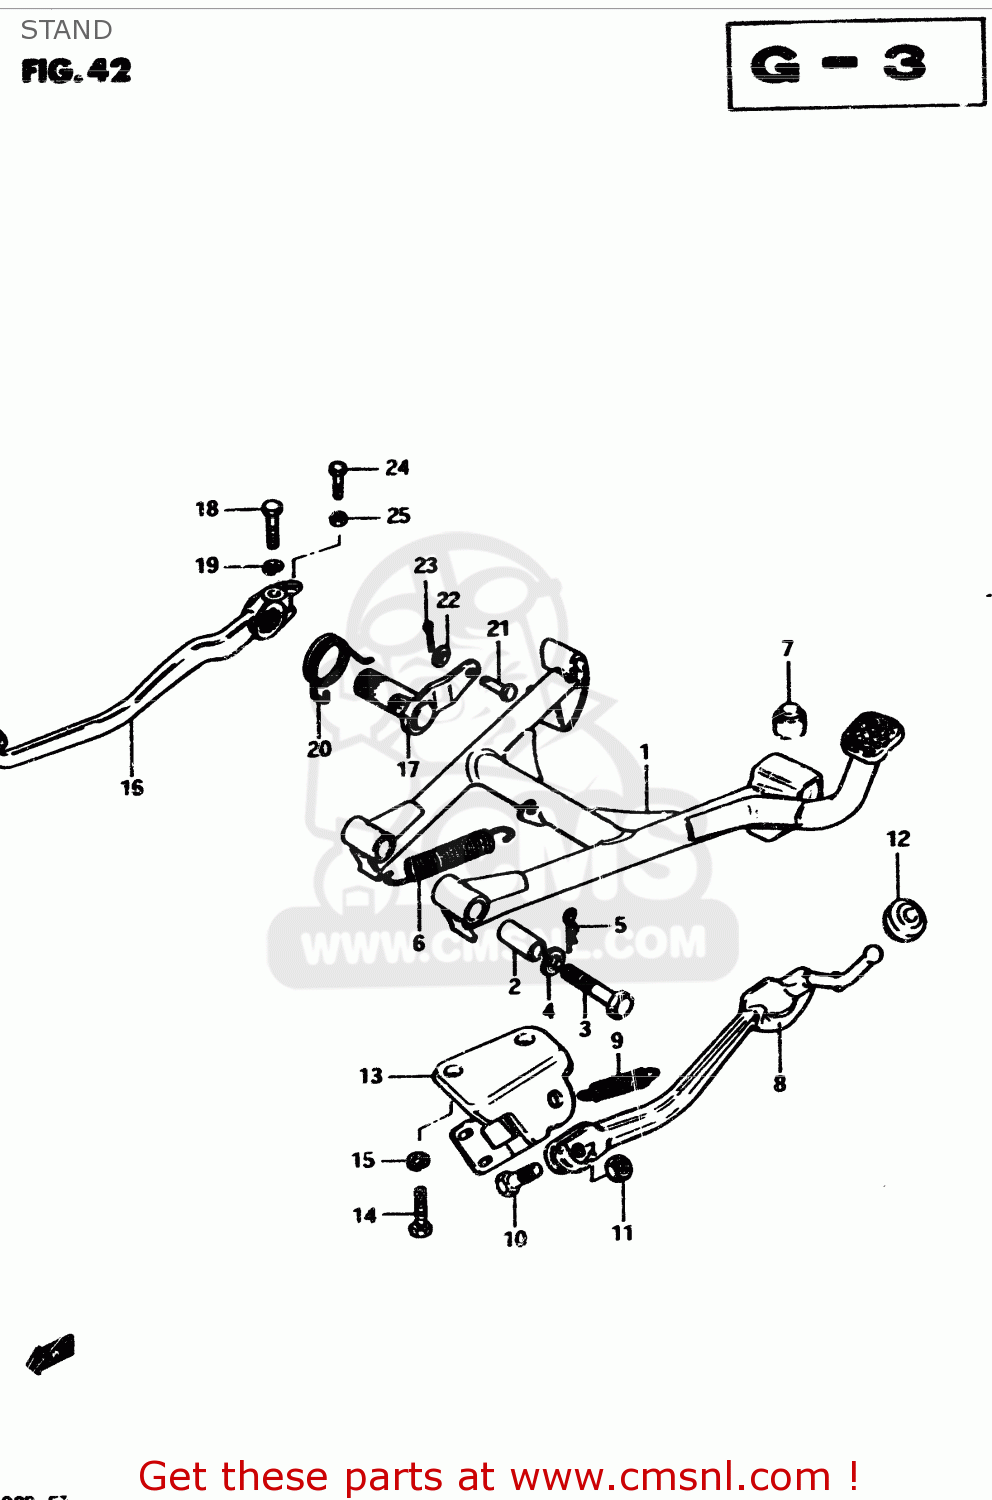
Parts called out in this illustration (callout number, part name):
1	STAND,CENTER
2	SPACER(10X16X38.8)
3	BOLT
4	LOCK WASHER
5	CLIP
6	SPRING
7	CUSHION
8	STAND,SIDE
9	SPRING
10	BOLT(10X30)
11	NUT
12	CUSHION
13	BRACKET,SIDE STAND
14	BOLT
15	LOCK WASHER
16	PEDAL,BRAKE
17	ARM,BRAKE PEDAL ROD
18	BOLT (8X30)
19	LOCK WASHER
20	SPRING
21	PIN
22	PIN
23	WASHER
24	BOLT
25	NUT
